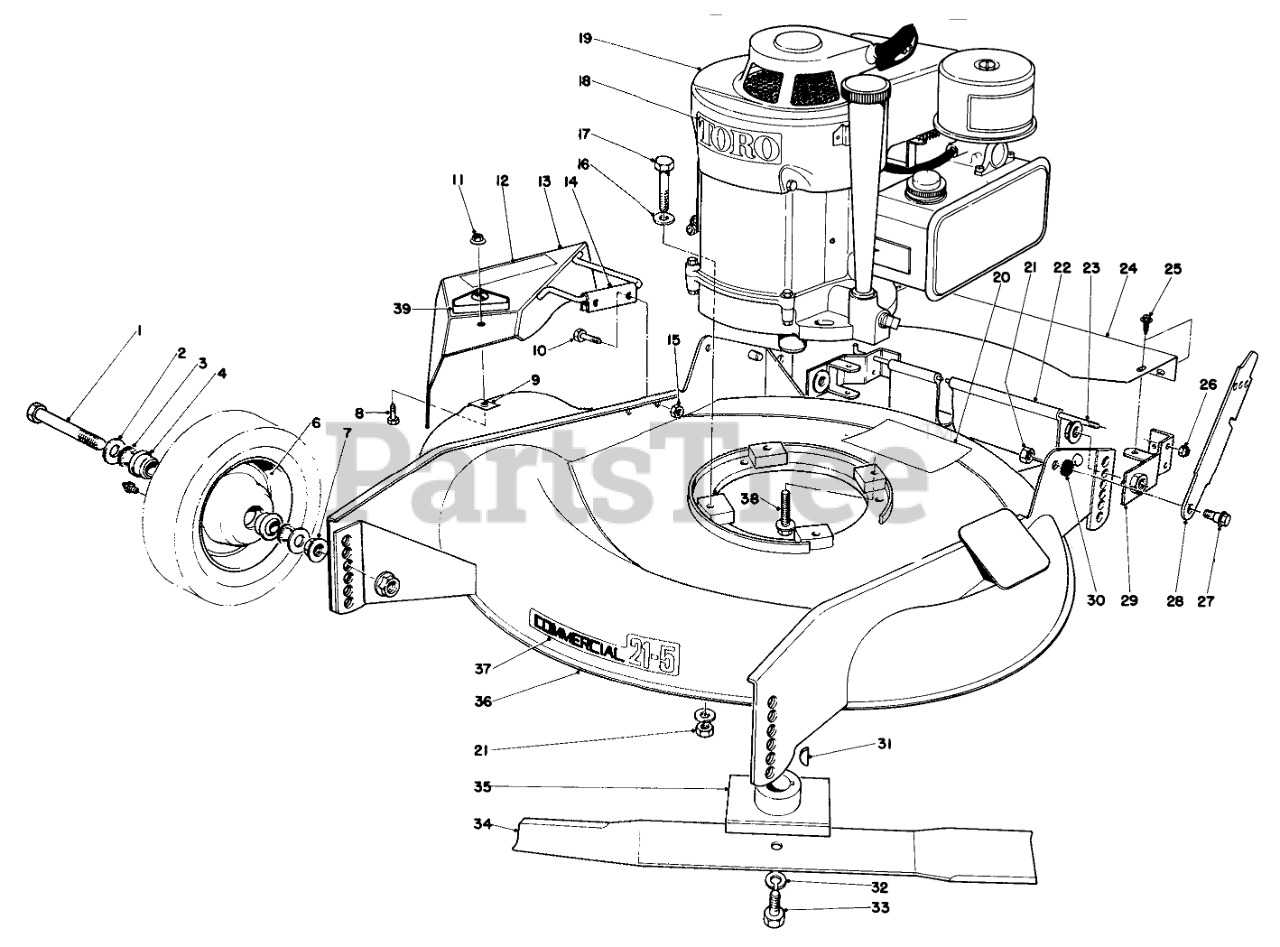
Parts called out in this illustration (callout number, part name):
1	SCREW-HH
2	WASHER-FLAT
3	FELT WASHER
4	BEARING-BALL
6	Wheel & Tire Assy. (Incl. Ref. #4)
7	NUT-HF
8	SCREW-HH
9	NUT-SPEED
10	SCREW-HH
11	NUT-LOCK, HHF
12	Decal
13	Deflector (Incl. Ref. #12 & 39)
14	Hinge-U Bracket
15	NUT-LOCK
16	WASHER-PLAIN
17	SCREW-HH
18	Decal Toro
19	Engine
20	Decal-Saftey Instruction
21	Nut
22	REAR SAFETY SHIELD
23	SHIELD ROD
24	Cover
25	10-16 X 3/8 THDG SCREW
26	NUT-LOCK, NI
27	SCREW-SHOULDER
28	HANDLE LATCH
29	WHEEL AXLE BRACKET WA
30	SPACER
31	KEY-WOODRUFF
32	WASHER-LOCK
33	SPECIAL SCREW
34	BLADE
35	BLADE RETAINER WA
36	Housing (Incl. Ref. #20 & 37)
37	Decal-Commercial 21-5
38	SCREW-HWHTF
39	DECAL-DANGER
